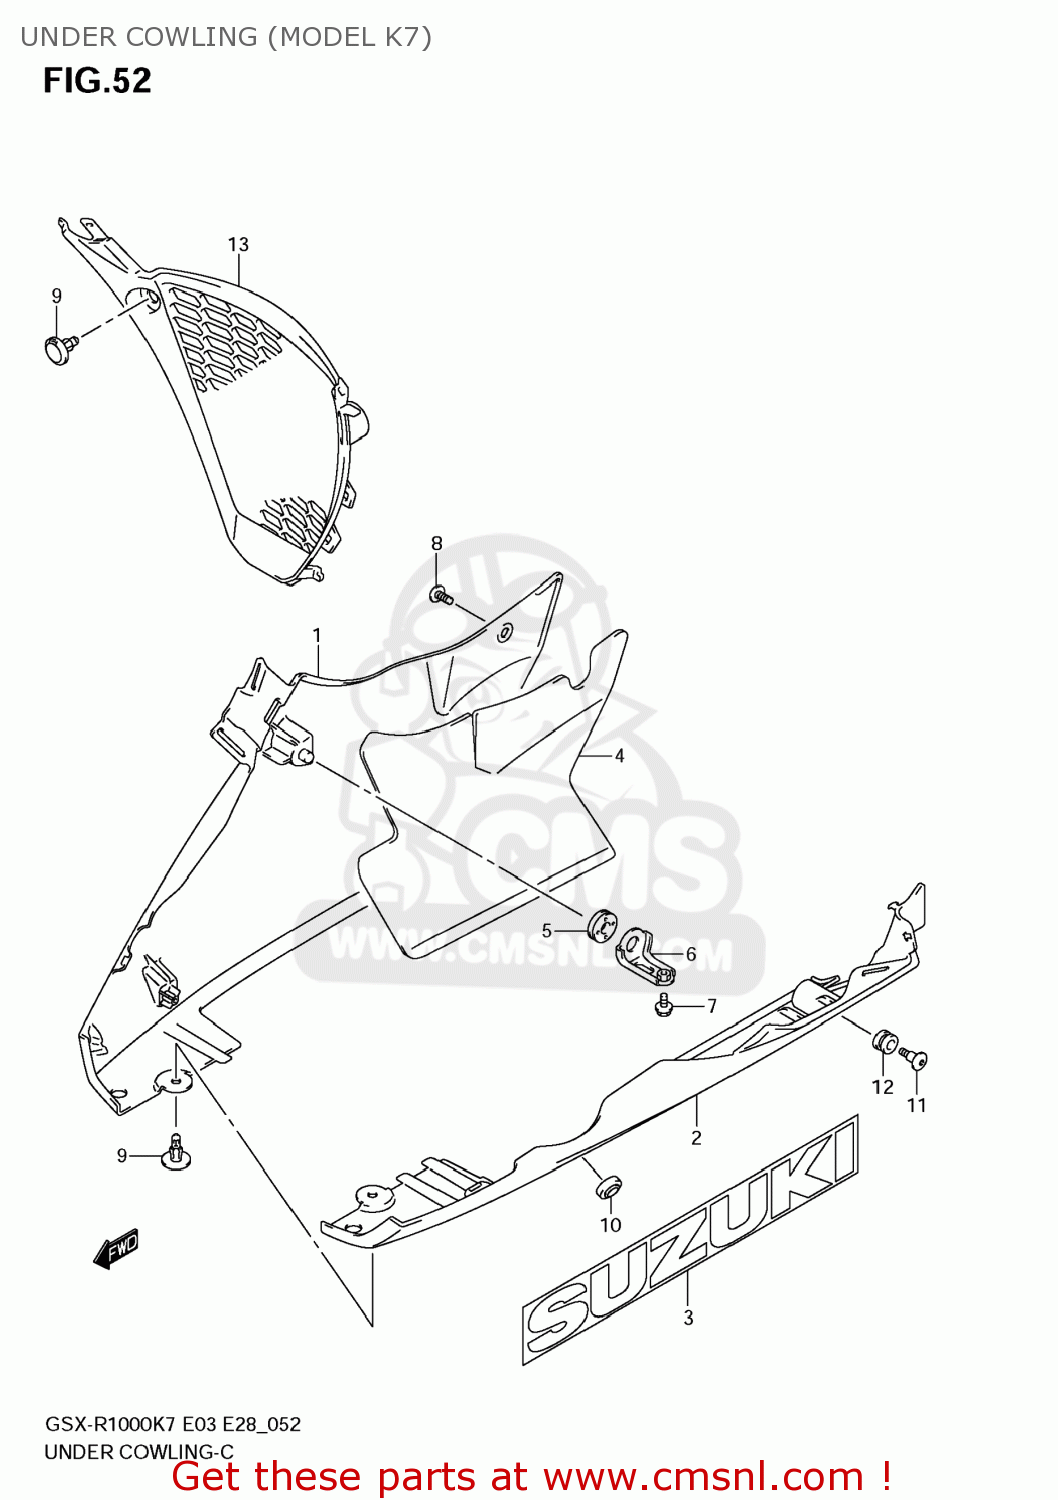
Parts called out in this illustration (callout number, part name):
1	COWLING,UNDER,R(BLACK)
2	COWLING,UNDER,L(BLACK)
3	EMBLEM,SUZUKI
4	SHIELD,UNDER COWL HEAT,R
5	CUSHION
6	BRACKET,UNDER COWLING LWR,L
7	BOLT
8	SCREW(5X13)
9	CLIP
10	CUSHION
11	SCREW(6X20)
12	CUSHION
13	COWLING,UNDER CTR
